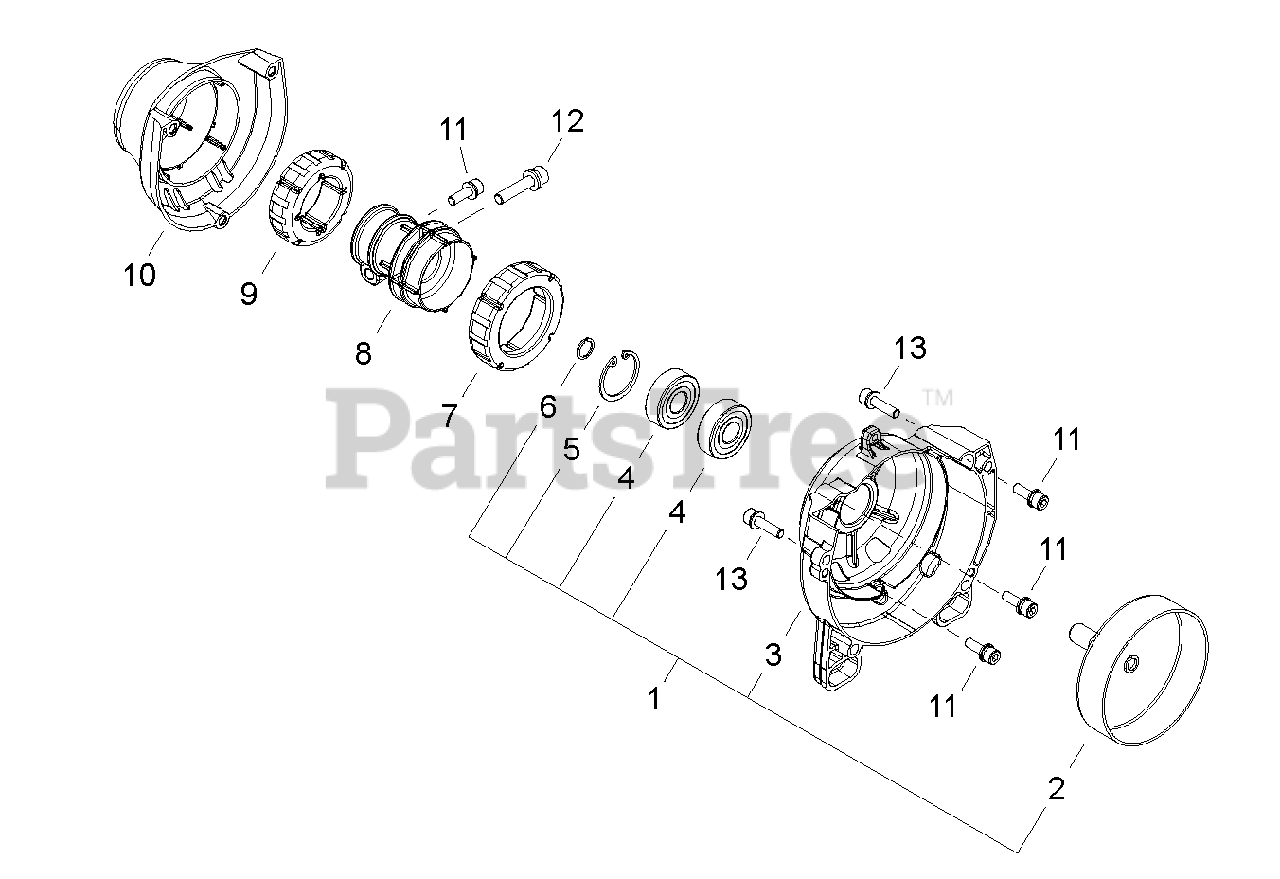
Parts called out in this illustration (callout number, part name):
1	COVER ASSY, FAN
2	DRUM, CLUTCH
3	COVER, FAN
4	BEARING, BALL 6001 DDU C3
5	RING, SNAP Ø28
6	RING, SNAP Ø12
7	HOLDER, REAR CUSHION
8	CUSHION
9	HOLDER, FRONT CUSHION
10	COVER, AV CUSHION
11	BOLT M5×16
12	BOLT M6×28
13	BOLT M5×20
